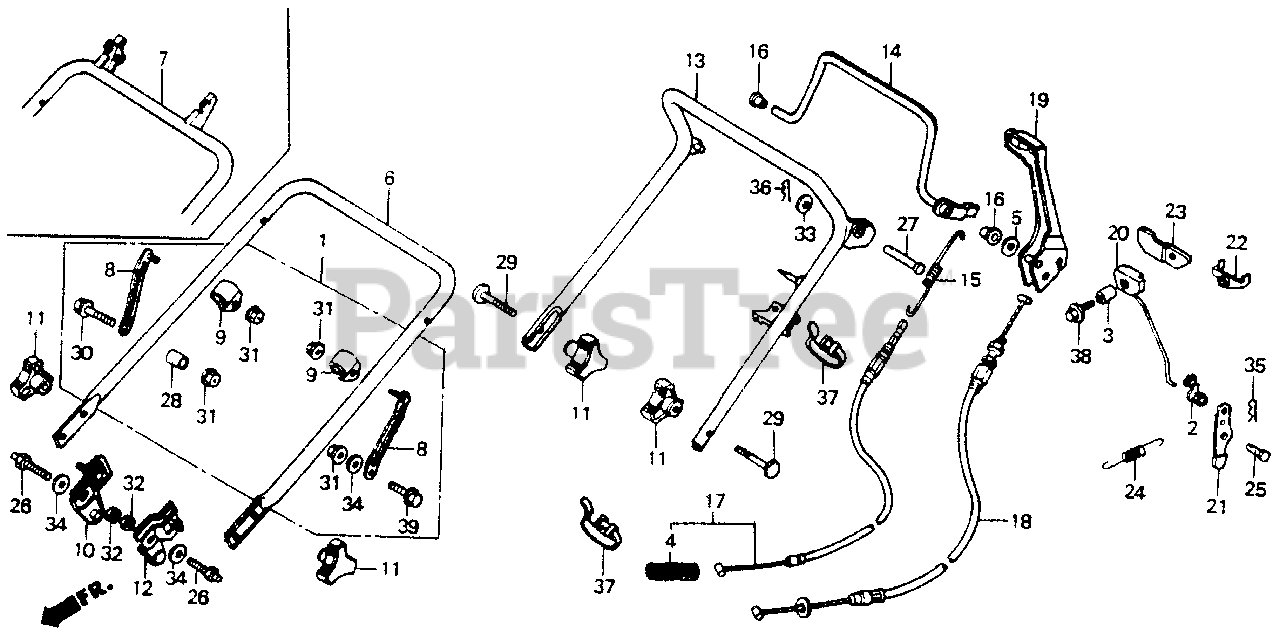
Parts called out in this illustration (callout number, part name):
1	SUPPORT KIT, HANDLE
2	JOINT, ROD
3	COLLAR, FAN
5	WASHER, EQUALIZER (NOT AVAILABLE)
6	PIPE, HANDLE (LOWER) (CHROME)
6	PIPE, HANDLE (LOWER) *NH105* (MAT BLACK)
8	PLATE, HANDLE SUPPORT
9	HANGER, HANDLE SUPPORT
10	STAY, R. HANDLE
11	GRIP, HANDLE JOINT (UPPER)
12	STAY, L. HANDLE
13	PIPE, HANDLE (UPPER)
18	CABLE, ROTO-STOP
19	LEVER, ROTO-STOP
20	ROD, RATCHET PUSH
21	LEVER, LOCK
22	PLATE, PUSH ROD
24	SPRING, RATCHET RETURN
25	PIN, SEAT HINGE
26	BOLT, HANDLE HOOK
27	PIN, CLUTCH LEVER
28	COLLAR, HANDLE SUPPORT
29	BOLT, HANDLE HOLDER
30	BOLT, FLANGE (8X37)
31	NUT, FLANGE (8MM)
32	NUT, SELF-LOCK (8MM)
32	NUT, HEX. (8MM)
34	WASHER, SPECIAL (22X8.5X2)
34	WASHER, PLAIN (8MM)
35	PIN, LOCK (6MM)
36	PIN, LOCK (8MM)
37	TIE, CABLE
37	BAND B2, CABLE HARNESS
38	BOLT, FLANGE (6X10)
39	BOLT, FLANGE (8X16)
